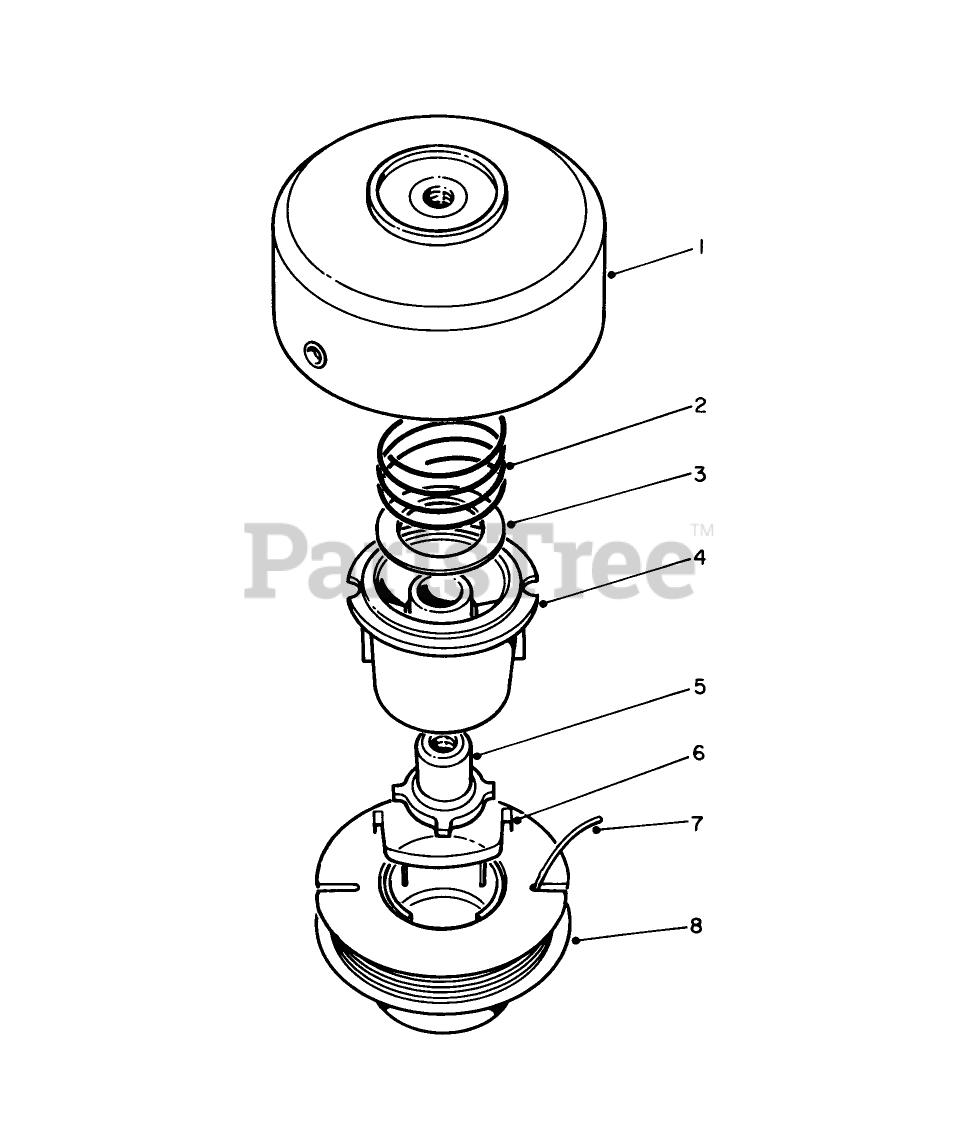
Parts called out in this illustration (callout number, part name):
1	Drum Assembly
2	SPRING
3	WASHER-FLAT
4	SPOOL CORE
5	LH DRIVER
6	SADDLE-SPOOL CAP
7	#1 BULK SPOOL .095
8	Prewound Spool
